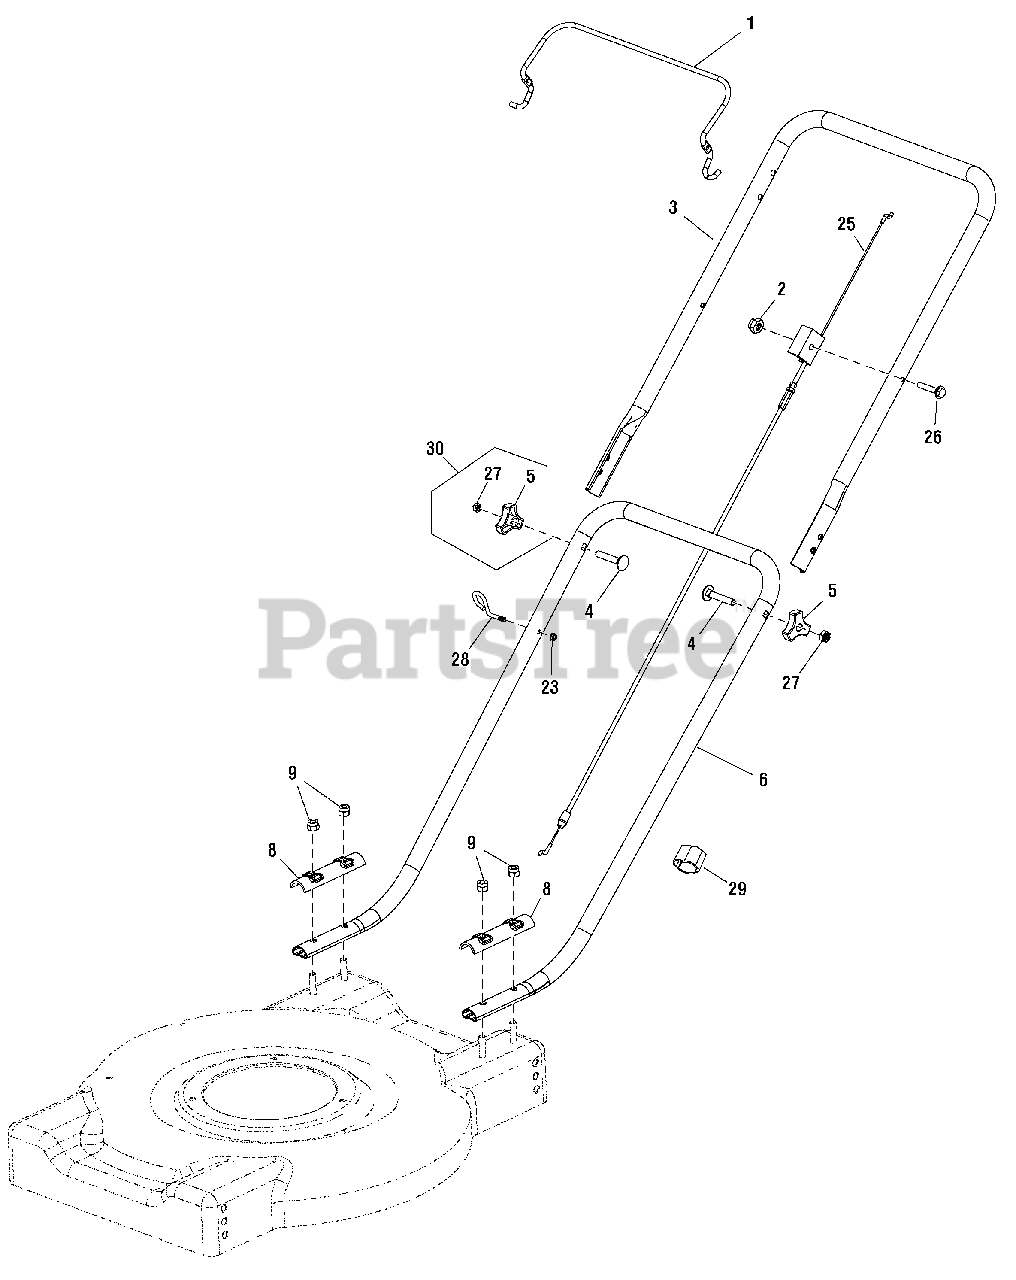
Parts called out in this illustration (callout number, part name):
2	NUT, M6
3	HANDLE, Upper
4	BOLT, Carriage, M8 x 45
6	HANDLE, Lower
8	PLATE, Saddle
9	NUT, M8
25	CABLE, Brake
26	BOLT, M6 x 35
27	NUT, M8
28	ROPE GUIDE
29	CLIP, Cable
30	KIT, Hardware, Knob
